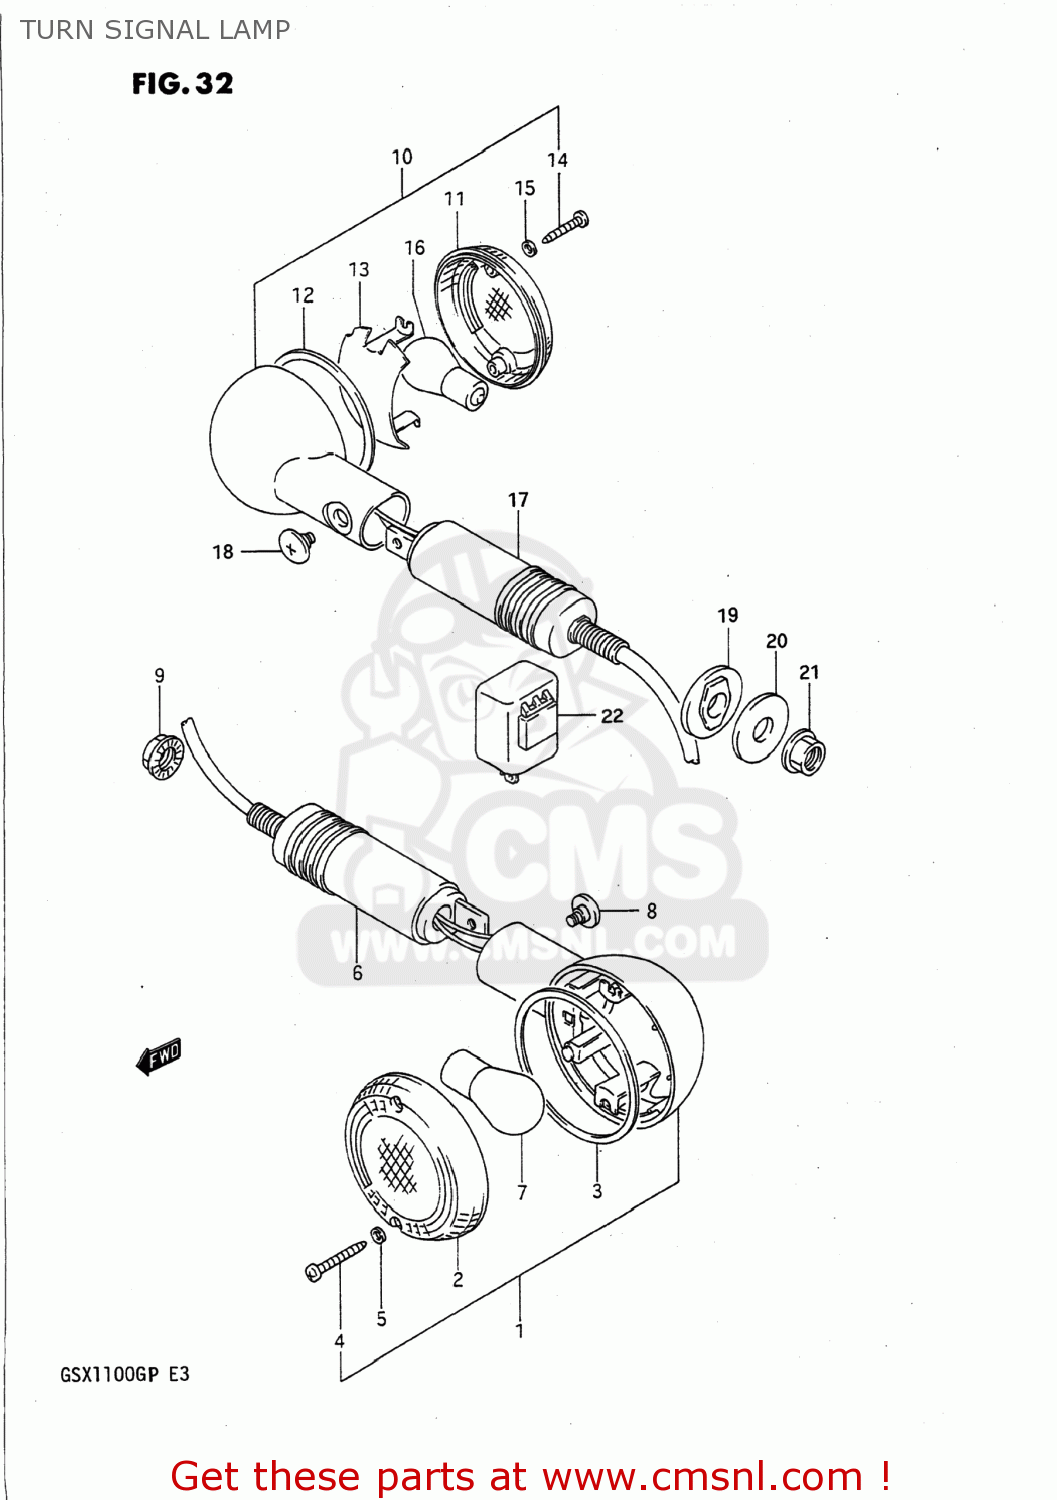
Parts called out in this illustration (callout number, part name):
1	LAMP ASSEMBLY,FRONT TURN SIGNAL
2	LENS
3	GASKET (NAS)
4	SCREW ,4X25
5	GASKET (NAS)
6	STAY,TURN SIGNAL,FRONT
7	BULB(12V21/5W,BF141-49642A)
8	SCREW
9	NUT
10	LAMP ASSEMBLY,REAR TURN SIGNAL
11	LENS
12	GASKET (NAS)
13	REFLECTOR
14	SCREW ,4X25
15	GASKET (NAS)
16	BULB(12V21W)
17	STAY,TURN SIGNAL,REAR
18	SCREW
19	SPACER,RR TURNSIGNAL
20	WASHER(10.5X30X3.2)
21	NUT
22	RELAY ASSEMBLY,TURN SIGNAL
